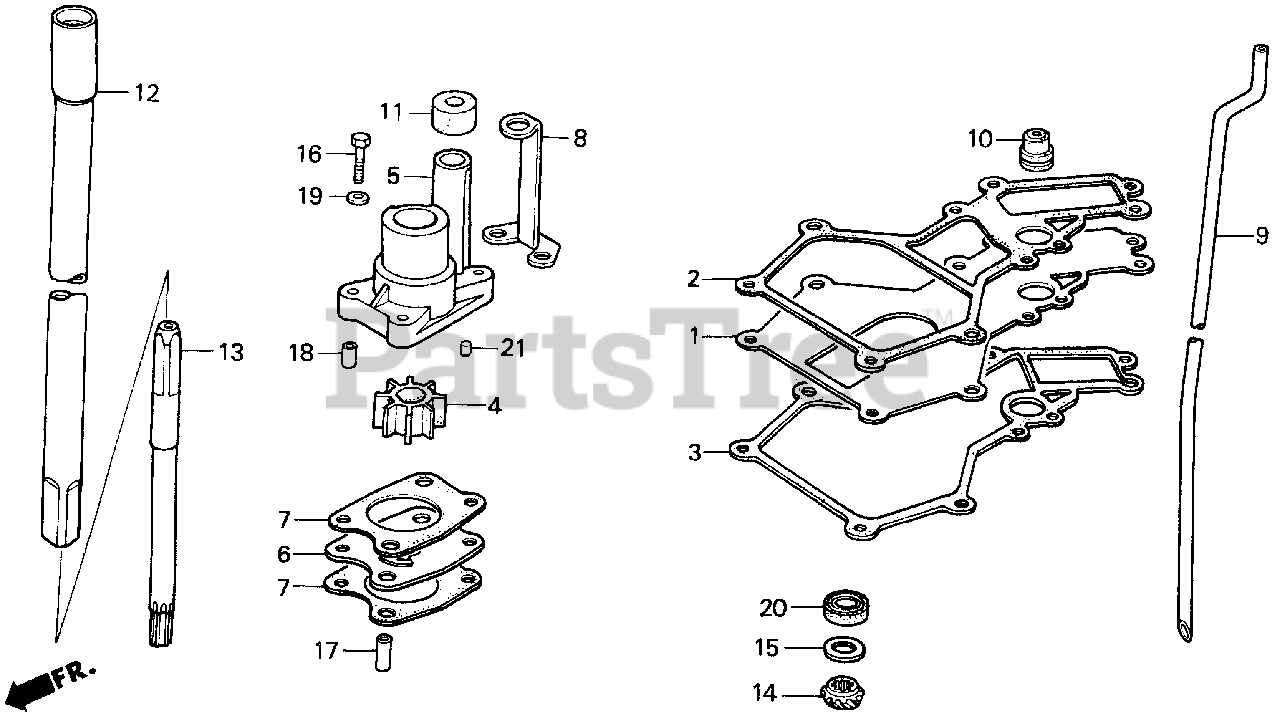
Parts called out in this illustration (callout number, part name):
1	PLATE, EX. CHAMBER
2	GASKET, EX. CHAMBER (UPPER)
3	GASKET, EX. CHAMBER (LOWER)
4	IMPELLER, PUMP
5	HOUSING, IMPELLER
6	COVER, IMPELLER
7	GASKET, IMPELLER
9	TUBE, WATER (L)
10	GROMMET, WATER TUBE
11	RING, WATER TUBE SEAL
12	SHAFT, VERTICAL (L)
13	SHAFT, PINION
15	WASHER A (1.00MM)
15	WASHER B (1.05MM)
16	BOLT, HEX. (6X28)
17	COLLAR B, DISTANCE
18	COLLAR B, DISTANCE
19	WASHER, PLAIN (6MM)
20	SEAL, WATER (13MM) (ARAI)
21	ROLLER (4X10)
